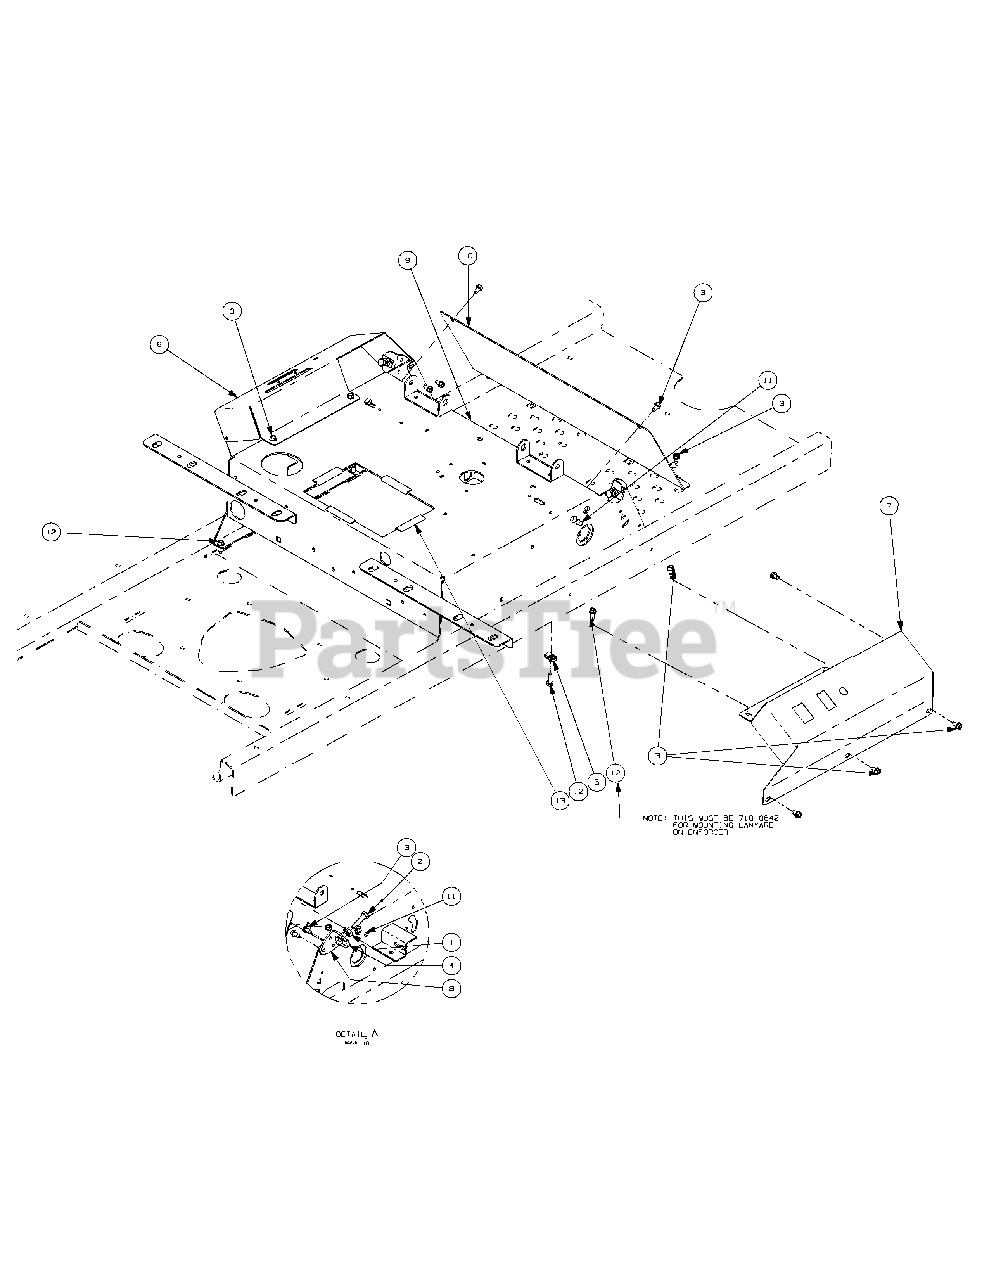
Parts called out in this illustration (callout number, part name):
1	Hex Nut, 5/16-18
2	HHCS, 5/16-18 x 1-1/4
3	Screw, 1/4-20 x 1/2
4	U-Nut, 5/16-18
5	U-Nut, 1/4-20
11	Self Tapping Screw 5/16-18 x .750
12	Self Tapping Screw, 1/4-20 x .75
13	Battery Edge Trim
